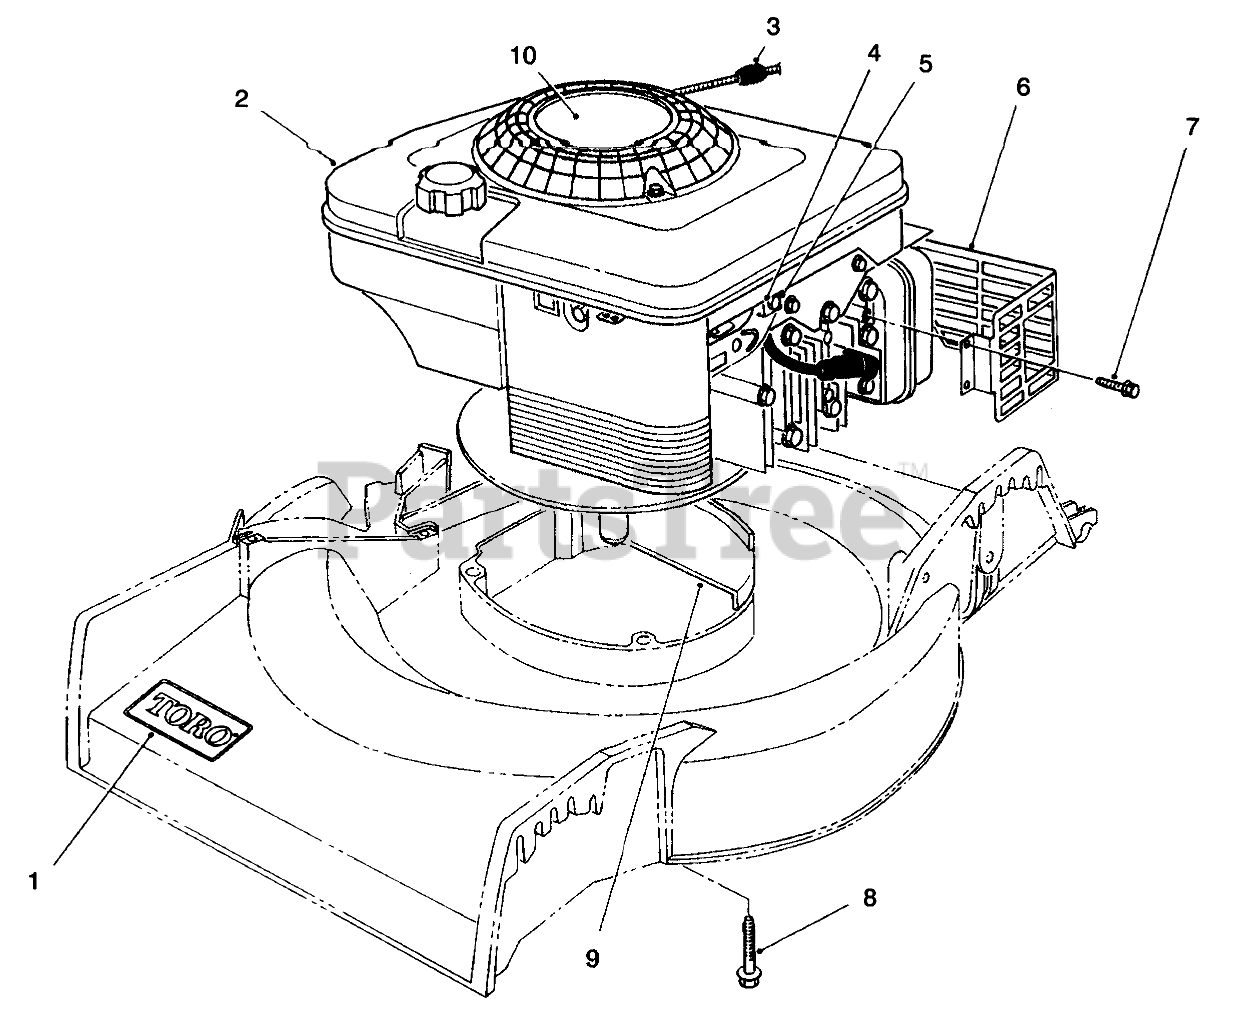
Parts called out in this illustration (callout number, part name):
1	DECAL
3	STOP-ROPE
4	CLAMP-CASING
5	SCREW-CLAMP
6	SHIELD-MUFFLER
7	SCREW-HWH
8	3/8-16 X 2-3/4 CAPSCR
9	HOUSING CAP
10	DECAL-ENGINE F/W ENGINE
